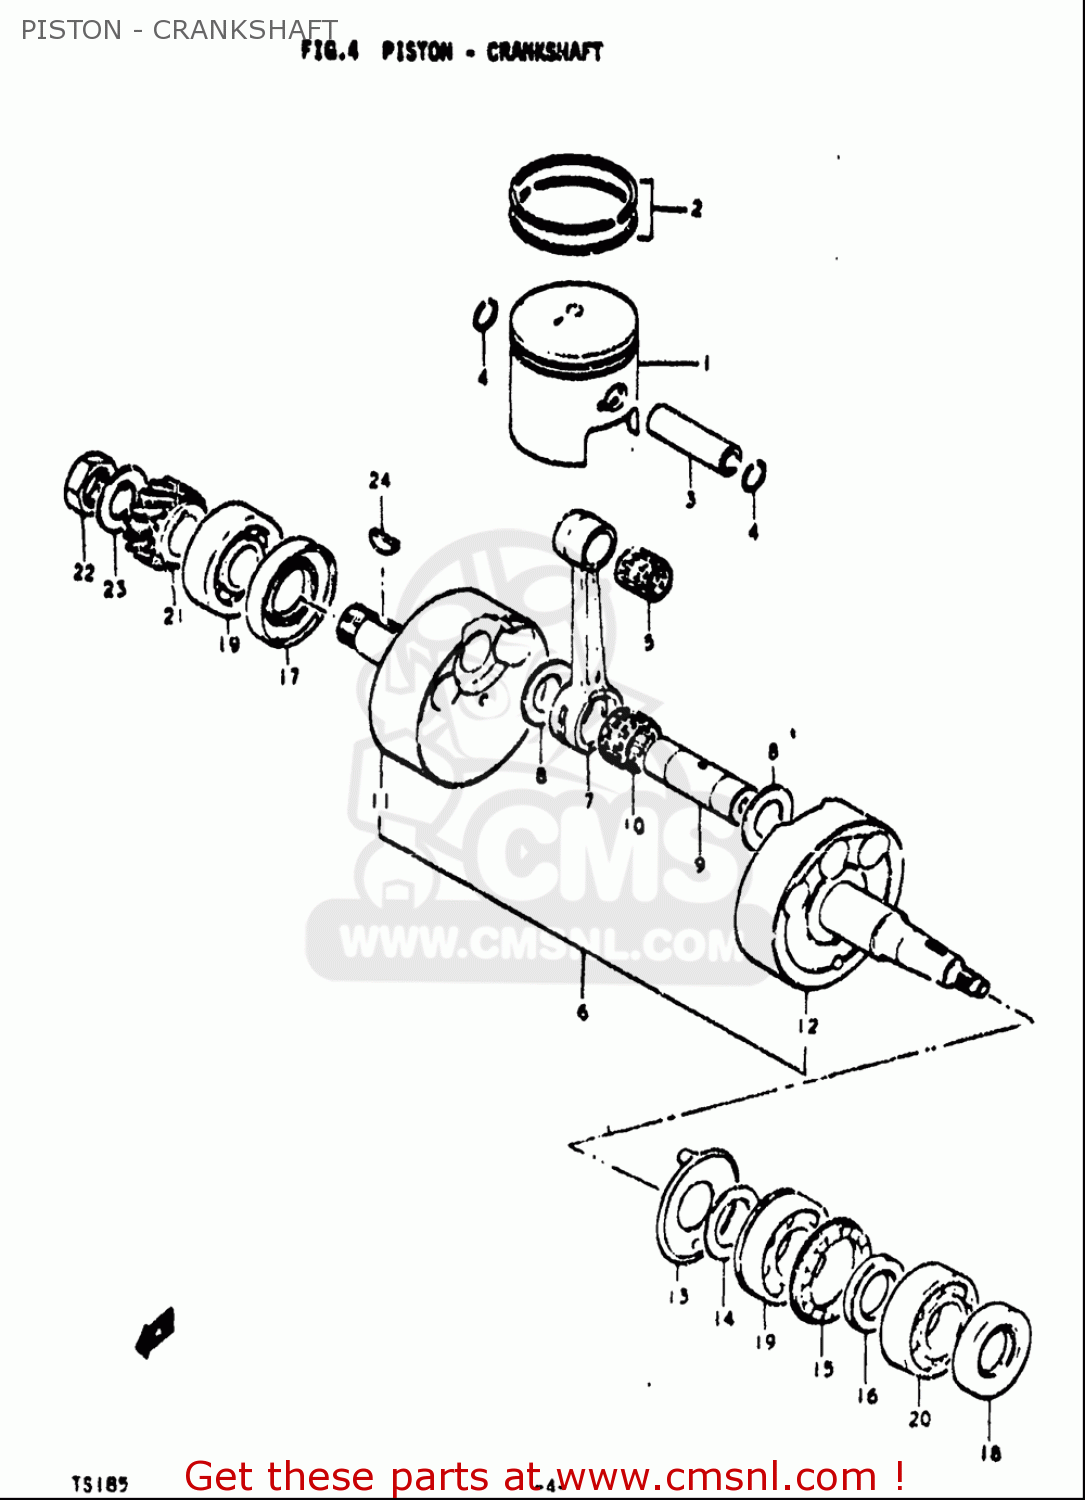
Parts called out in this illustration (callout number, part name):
1	PISTON
2	RING SET,PISTON
3	PIN,PISTON
4	RING,SNAP 16MM
5	BEARING(16X21X19.6)
7	ROD,CONNECTING
8	WASHER(22X35X1)
9	PIN,CRANK
10	BEARING(22X28X16)
15	SPACER,CRANKSHAFT,LEFT
16	SPACER
17	SEAL,OIL(26X52X8)
18	SEAL,OIL(25X44X7)
19	BEARING
20	BEARING(25X52X15)
21	GEAR,PRIMARY DRIVE
22	NUT
23	WASHER
24	KEY
